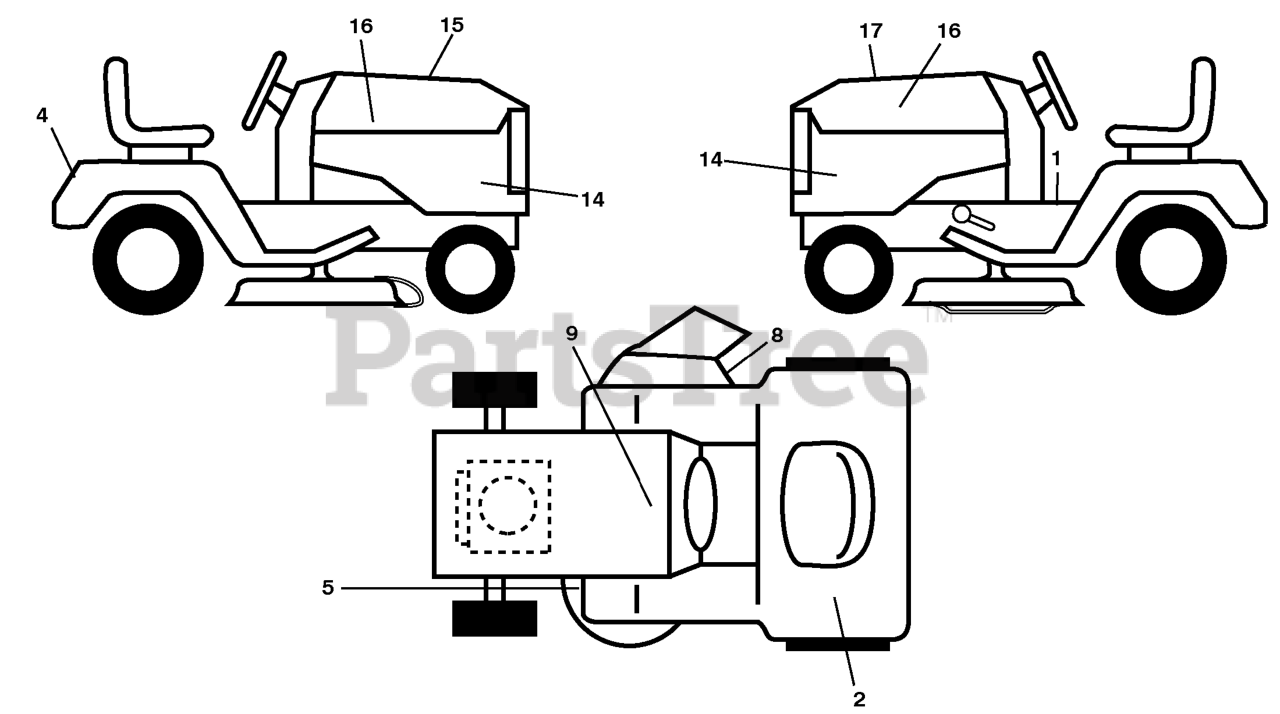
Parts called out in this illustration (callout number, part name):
1	DECAL.WARN.START.INSTRUCTIONS
2	DECAL,ETHANOL E85 WARNING
4	DECAL.FENDER
5	DECAL.MOWER
8	DECAL.MOWER.SCH.48/54
9	DECAL BTRY SYMBOLS
14	DECAL.PNL.SD.LGT2554.KOHL.
15	DECAL.WARNING.CUST.RESP.E85.
16	DECAL.HOOD.LOGO.ORANGE.HUSQVAR
17	DECAL.RPL.KHSV730.TGW.54.0610F
